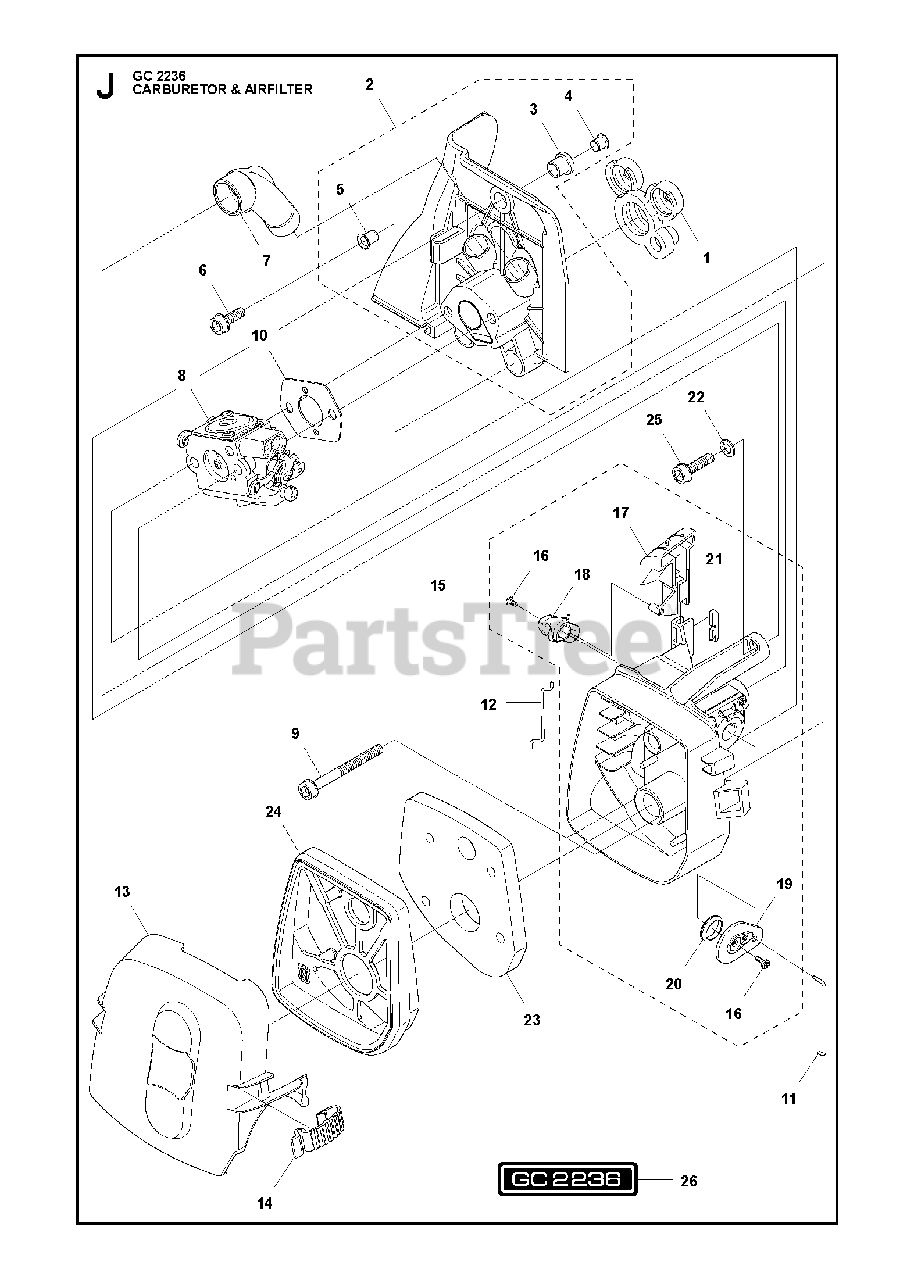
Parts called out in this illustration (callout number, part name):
2	PARTITION
3	SLEEVE
4	SLEEVE
5	SLEEVE
8	CARBURETOR C1QEL36
11	THROTTLE ROD
12	THROTTLE ROD
13	COVER AIR FILTER
15	FILTER HOLDER
16	SCREW
17	CHOKE CONTROL
18	LEVER
19	LEVER
20	BELLOWS
21	RAIL
23	AIR FILTER
